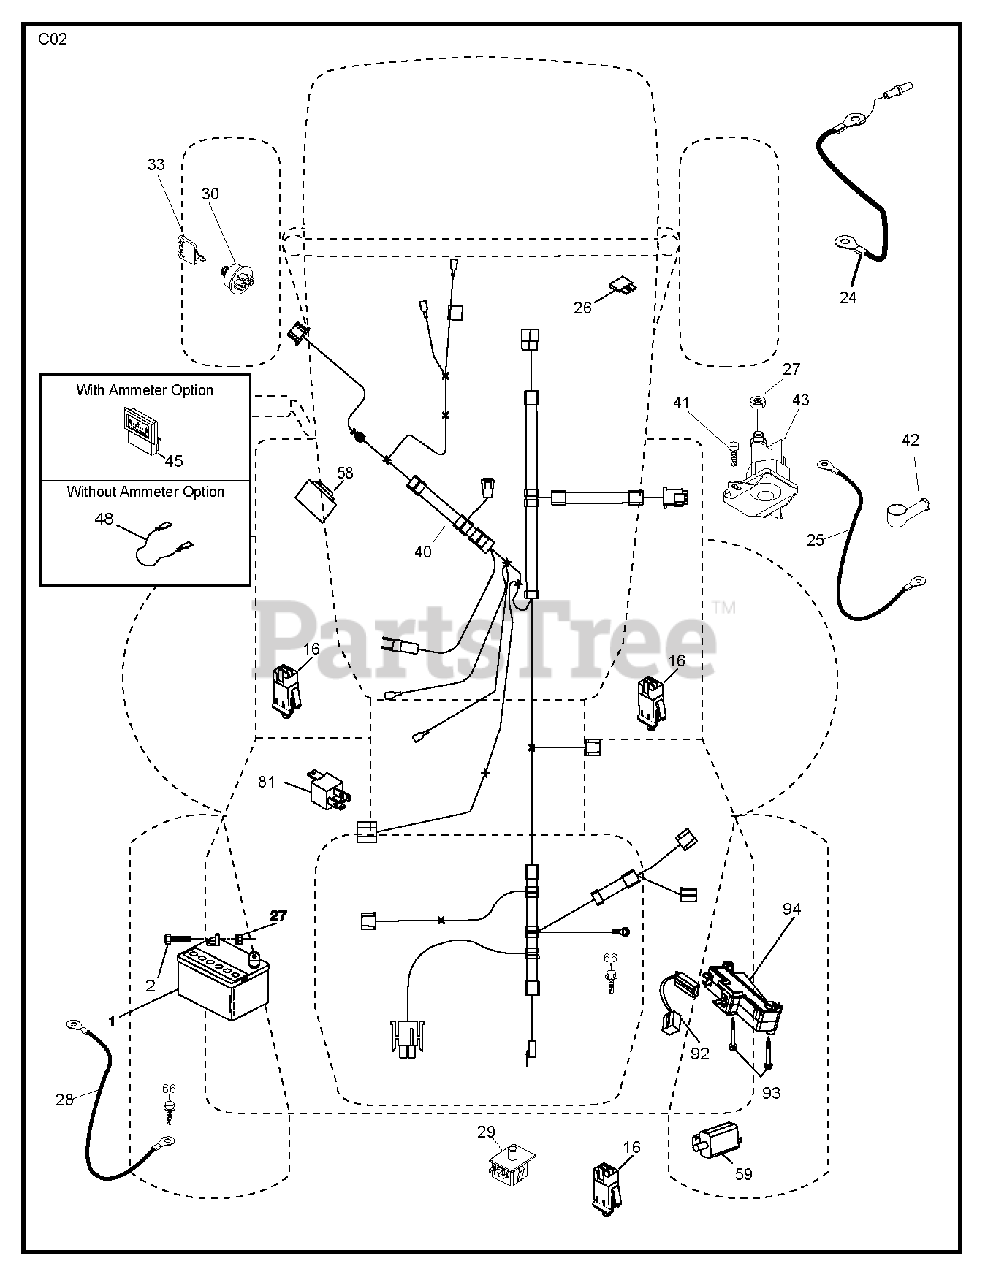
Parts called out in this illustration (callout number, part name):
1	REPL BY 532 12 38-99
2	BOLT.HEX.1/4.X.3/4.DICHROMATE
16	SWITCH INTERLOOK PUSH-IN
24	CABLE BATTERY
25	CABLE.STARTER.6GA.11"RED
26	FUSE 20AMP
27	NUT
29	SWITCH.SEAT.DP W/RAMPS
30	SWITCH.IGN.DELTA.W.LGH.ROS
33	KEY.CHAIN.BLISTER.PACK.GEN.INT
41	BOLT
42	TERMINAL COVER
43	SOLENOID.W/BRASS.PLUNGER
48	ADAPTER.AMMETER
66	SCREW LT
81	RELAY.ASSY.T
92	HARNESS.PIGTAIL.CONSLE
93	SCREW.PLASTITE
94	MODULE.REVERSE.ROS
